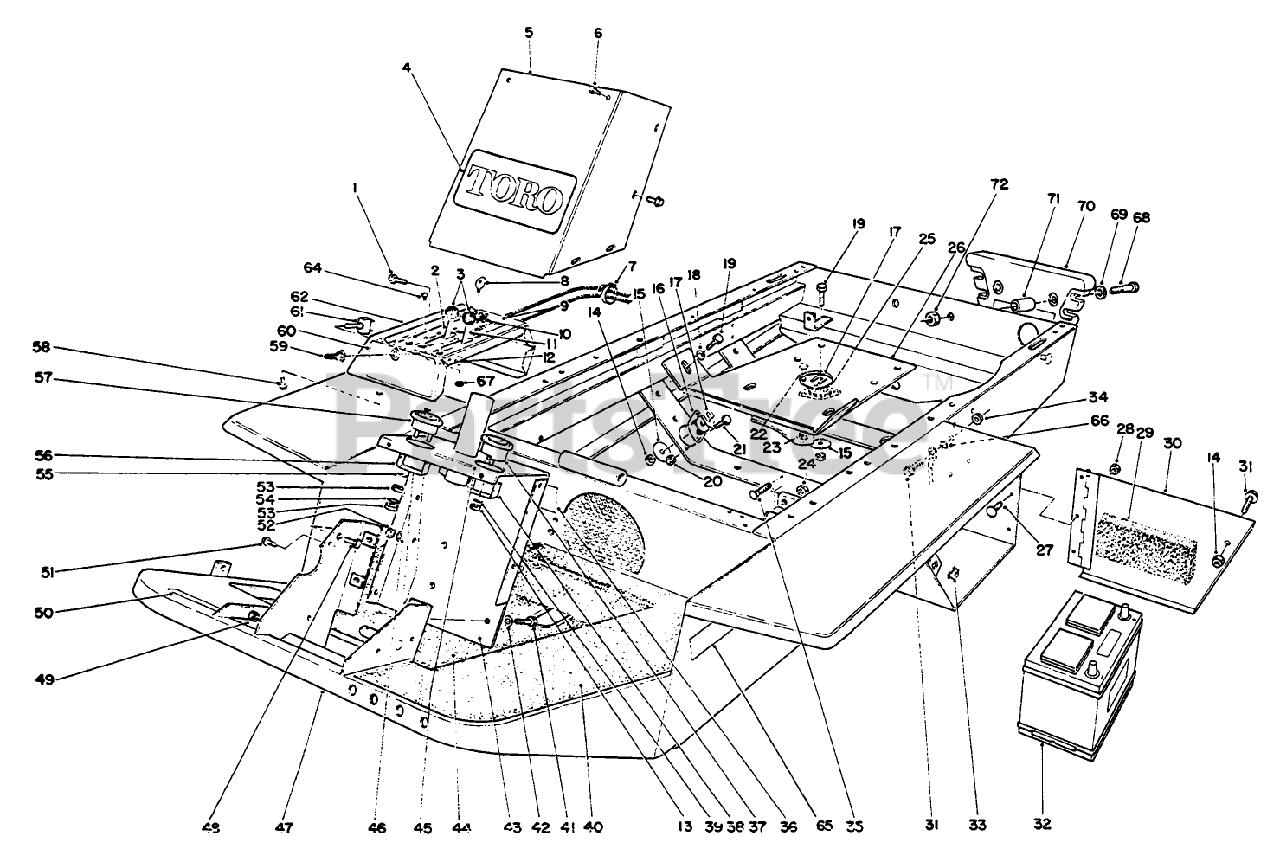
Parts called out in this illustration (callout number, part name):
1	SCREW-HHF
2	CHOKE CONTROL
4	DECAL
5	Tower Cover
6	SCREW-HHFTF
7	TIE-CABLE
8	KEY-IGNITION
9	DECAL - INST. PANEL
10	SWITCH
11	THROTTLE CONTROL
12	WASHER-FLAT
13	NUT-HEX
14	NUT-LOCK, NI
15	WASHER-REBOUND
16	ENGINE RUBBER MT
17	SHIM-AXLE
18	WASHER-FLAT
19	SCREW-HH
20	NUT-LOCK, NI
21	SCREW-HH
23	NUT-LOCK, NI
24	NUT-JAM
25	RUBBER MOUNT
26	Base-Engine
27	SCREW-HSBH
28	NUT-LOCK, NI
29	BATT BOX FOAM
30	Battery Cover
31	SCREW-HHF
32	Assembly-Battery
33	RETAINER NUT
34	NUT-HHF, WHIZ
35	SCREW-CARR
36	DECAL-OIL
37	HOUR METER
38	BRACKET F/W
39	WASHER-LOCK, INT
40	NON SKID (TUNNEL)
41	SCREW-HH
42	WASHER-LOCK
43	Steering Post
44	NON-SKID-FLOOR
45	INSTRUCTION DECAL
46	WASHER-LOCK
47	Frame Assembly
48	SCREW-HHF
49	NUT-LOCK, NI
50	DECAL-PEDAL, TRACTION
51	SCREW-HWH
52	NUT-HEX
53	NUT-HEX
54	WASHER-LOCK
55	WASHER-FLAT
56	MTG CLAMP F/W GUAGE
57	AMMETER GAUGE ASSY
58	SCREW-THD FRM,HWH
59	BOOT-SWITCH
60	BY-PASS DECAL
61	Switch-Toggle (Incl. Ref. #58)
62	Instrument Panel
64	10-24 X 5/8 PAN HD MS
65	CAUTION DECAL
66	WASHER-LOCK
67	NUT-KEPS
68	SCREW-HH
69	WASHER-LOCK
70	WEIGHT-REAR
72	NUT-HH
